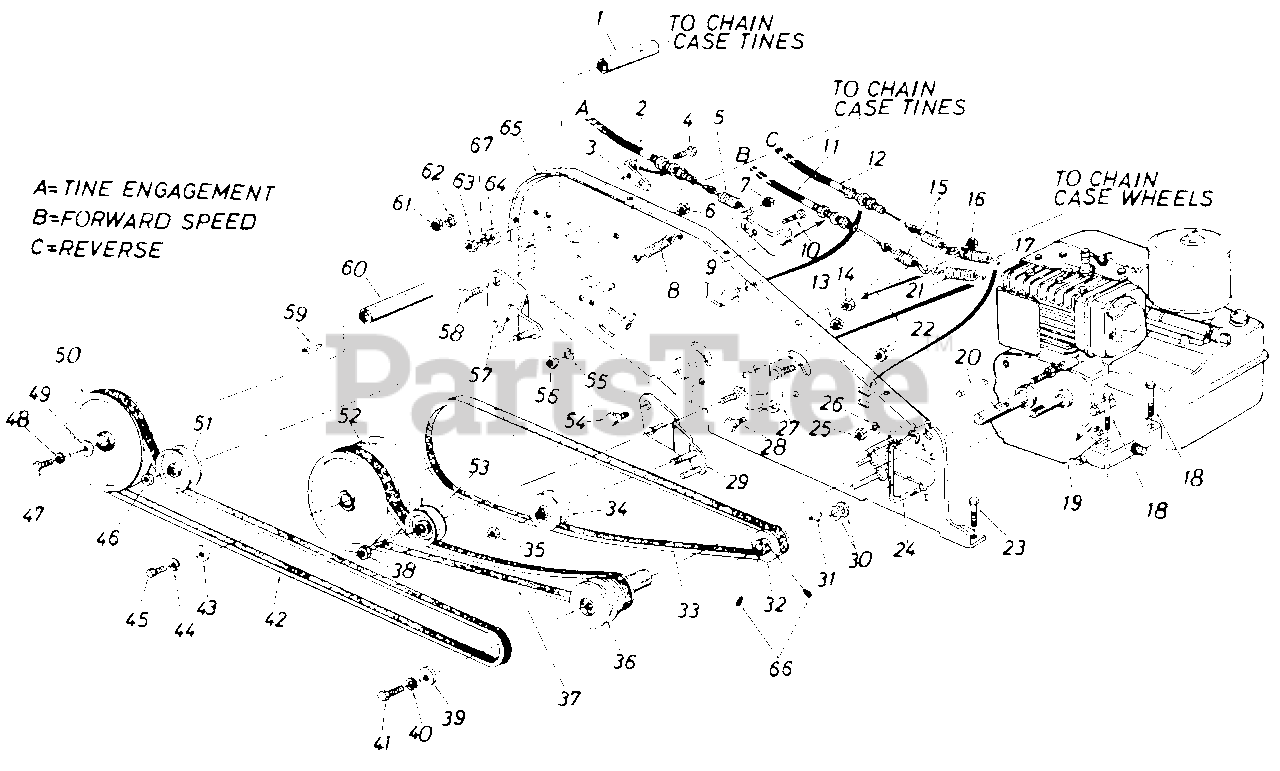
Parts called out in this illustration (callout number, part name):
1	Spacer.375" I.D. x .500" O.D. x 2.00" Lg.
2	Clutch Control Cable
3	Clutch Cable Bracket
4	Hex Bolt 5/16-18 x .75" Lg.
5	Extension Spring .50" O.D. x 2.50" Lg.
6	Hex Cent. L-Nut 3/8-16 Thd.
7	Hex Cent. L-Nut 1/4" Thd.
8	Extension Spring .50" O.D. x 1.55" Lg.
9	Clutch Cable Bracket
10	Hex Bolt 5/16-18 x .75" Lg.
11	Clutch Control Cable 42" Lg.
12	Clutch Control Cable 41" Lg.
13	Hex Cent. L-Nut 3/8-16 Thd.
14	Hex Cent. L-Nut 1/4-20 Thd.
15	Springs
16	Hex Cent. L-Nut 1/4-20 Thd.
17	Extension Spring .41" O.D. x 2.05" Lg.
18	Hex Bolt 5/16-18 x 1.50" Lg.
20	Sq. Key 3/16 x 1.00" Lg.
21	Extension Spring .50" O.D. x 2.75" Lg.
22	Hex Cent. L-Nut 3/8-16 Thd.
23	Hex Bolt 5/16-18 x .75" Lg.
24	Belt Keeper
25	Hex Nut 1/4-20 Thd.
26	Bell-Wash. .265" I.D. x .75" O.D.
31	#5 Hi-Pro-Key 1/8" x 5/8" Dia.
32	1/2" V-Pulley 2.25" O.D. x .503" I.D.
33	"V"-Belt 1/2" x 43.0" Lg.
34	"V"-Belt Idler 2.62" O.D.
35	Hex Ins. L-Nut 3/8-24 Thd.
36	1/2" "V "-Pulley Ass'y.
37	"V"-Belt 1/2" x 39.0" Lg.
38	Hex Ins. L-Nut 3/8-24 Thd.
39	Fl-Wash. .344" I.D. x 1.125" O.D.
40	L-Wash. 5/16" I.D.
41	Hex Bolt 5/16-24 x 1.00" Lg.
42	"V"-Belt 1/2" x 54.0" Lg.
43	Fl-Wash. 1/4" I.D. x .93" O.D.
44	L-Wash. 1/4" I.D.
45	Hex Bolt 1/4-28 x .75" Lg.
46	Hex Ins. L-Nut 3/8-24 Thd.
47	Hex Bolt 1/4-28 x .75" Lg.
48	LWash. 1/4" I.D.
49	Fl-Wash. 1/4" I.D. x .93" O.D.
50	Fl-Pulley w/Flanges 6.0"
51	Fl-Idler w/Flanges 3.75" O.D.
52	Double Fl-Pulley 5/8" I.D. x 6.0" O.D.
53	Fl-Idler with Flanges 2.12" O.D.
54	Shld. Bolt .500" Dia. x .170" Lg.
55	L-Wash. 5/16" I.D.
56	Hex Nut 5/16-18 Thd.
59	#61 Hi-Pro-Key 3/16" x 5/8" Dia.
60	Spacer .647" I.D. x 2.75" Lg.
61	Hex Nut 5/16-18 Thd.
62	L-Wash. 5/16" I.D.
63	Hex Nut 5/16-18 Thd.
64	Fl-Wash. .406" I.D. x .750" O.D.
65	Side Plate Ass'y.
66	Set Scr. 1/4-28 x .25" Lg.
67	L-Wash. 5/16" I.D.
